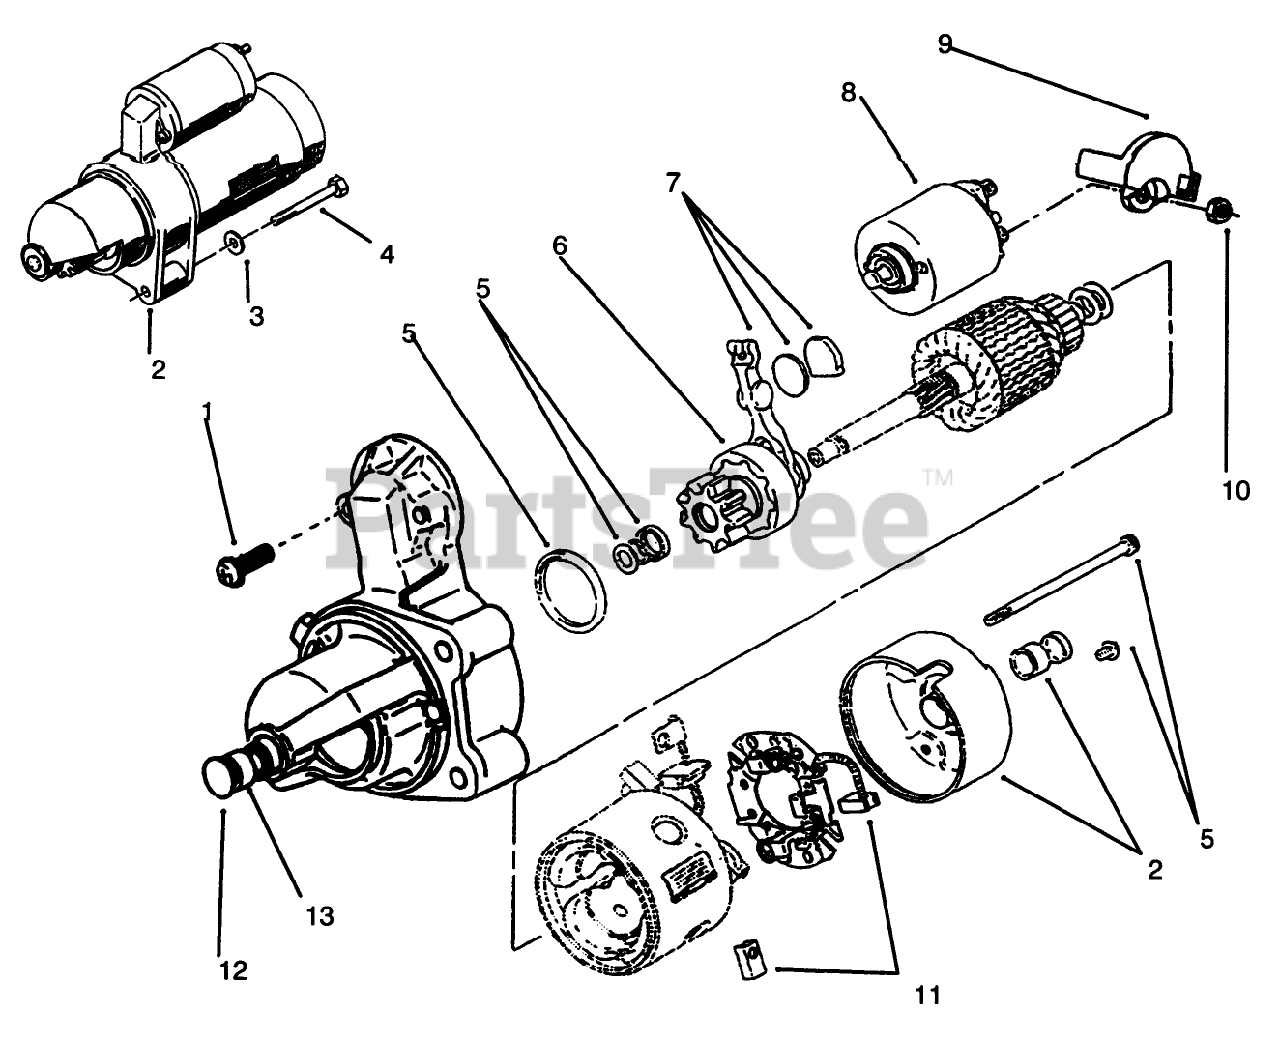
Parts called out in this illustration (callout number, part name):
3	WASHER
6	CLUTCH STARTER ASSEMBLY
8	STARTER SOLENOID KIT
10	O-RING
12	BUSHING
13	KIT-MTG BRKT
